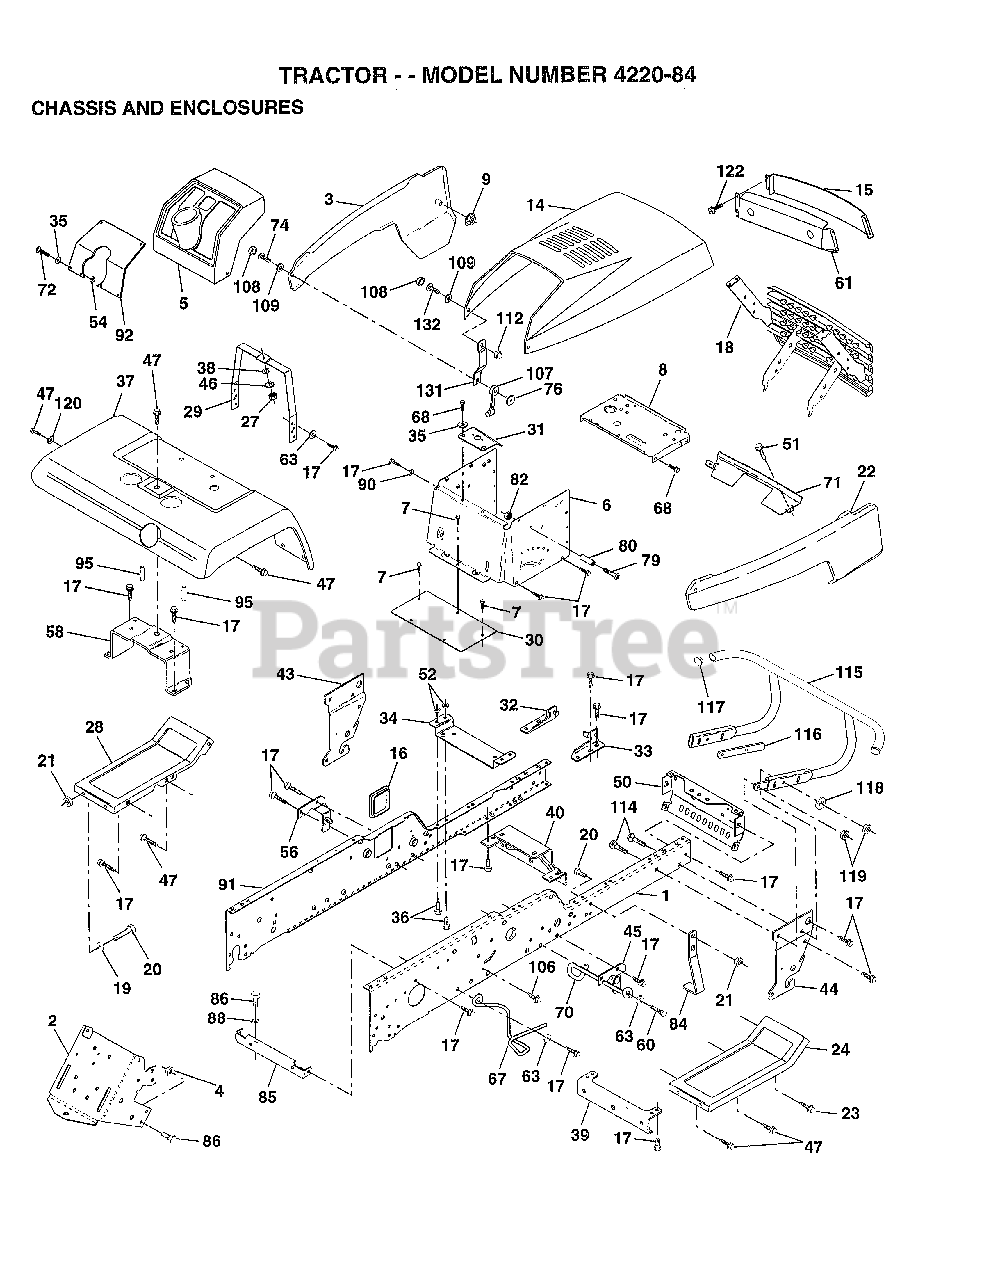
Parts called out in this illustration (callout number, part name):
1	"RAIL,FRAME RH"
2	DRAWBAR GT
3	PANEL ASM SIDE LH
4	NUT.7/16
5	DASHBOARD BLACK
6	DASH LOWER
7	SCREW
8	SUPPORT.DASH.BTRY
9	PAL NUT LT
15	LENS.BAR.CLEAR
16	COVER ACCESS
17	SCREW
19	WASHER
20	BOLT
22	PANEL ASM SIDE RH
23	SCREW GTV
24	FOOTREST.RH.LT/GT
28	FOOTREST.LH.LT/GT
29	DASH.SUPT.YP/HUSQ
30	SADDLE.SCR.6SP
31	BRKT SUPT 1-PC VG
32	BRACKET ASM FRAME
33	BRACKET ASM FRAME
34	BRACKET.ENG.SUPT.
35	WASHER
36	BOLT
38	LOCKWASHER
39	BRACKET.AXLE.FRT.
40	"BRKT SUPPORT,AXLE"
43	BRACKET.SUS.FT.LH
44	BRACKET.SUS.FT.RH
45	BRACKET ASM., SUSP CHASSIS RH
46	WASHER PM
47	SCREW LT
50	"BRKT CHASSIS,FRNT"
51	SCREW
56	BRACKET.SUSP.LH.
58	BRKT.ASM.FENDER
60	SCREW
61	BEZEL.ASM.
63	WASHER
67	"GUIDE BELT, T/A"
70	GUIDE.BELT.MID.SP
71	STRAP.GRILLE.424
72	SCREW
74	SCREW
76	WELDNUT
79	SCREW
80	SPACER LT
84	STOP.OVER.CENTER
85	BRACKET.SUPT.TRAN
86	BOLT
88	LOCKWASHER
90	LOCKWASHER
91	"RAIL FRAME,LH"
92	"PLATE-DASH,SLKSCR"
95	NUT-PUSH YT
107	HOOD LATCH T
108	SNAP CAP LT
109	WASHER LT
112	ACORN NUT RB
114	BOLT.3/8-14X1.25
115	BUMPER.ASM
116	BRACKET.EXT.BUMP.
117	PLUG.PLASTIC
118	WASHER
120	WASHER HYT
122	SCREW.HEX.WS.HD
131	BKT.SPT.HOOD/PANL
132	SCREW.10-24X3/8.
137	BOLT.FIN.HEX.
